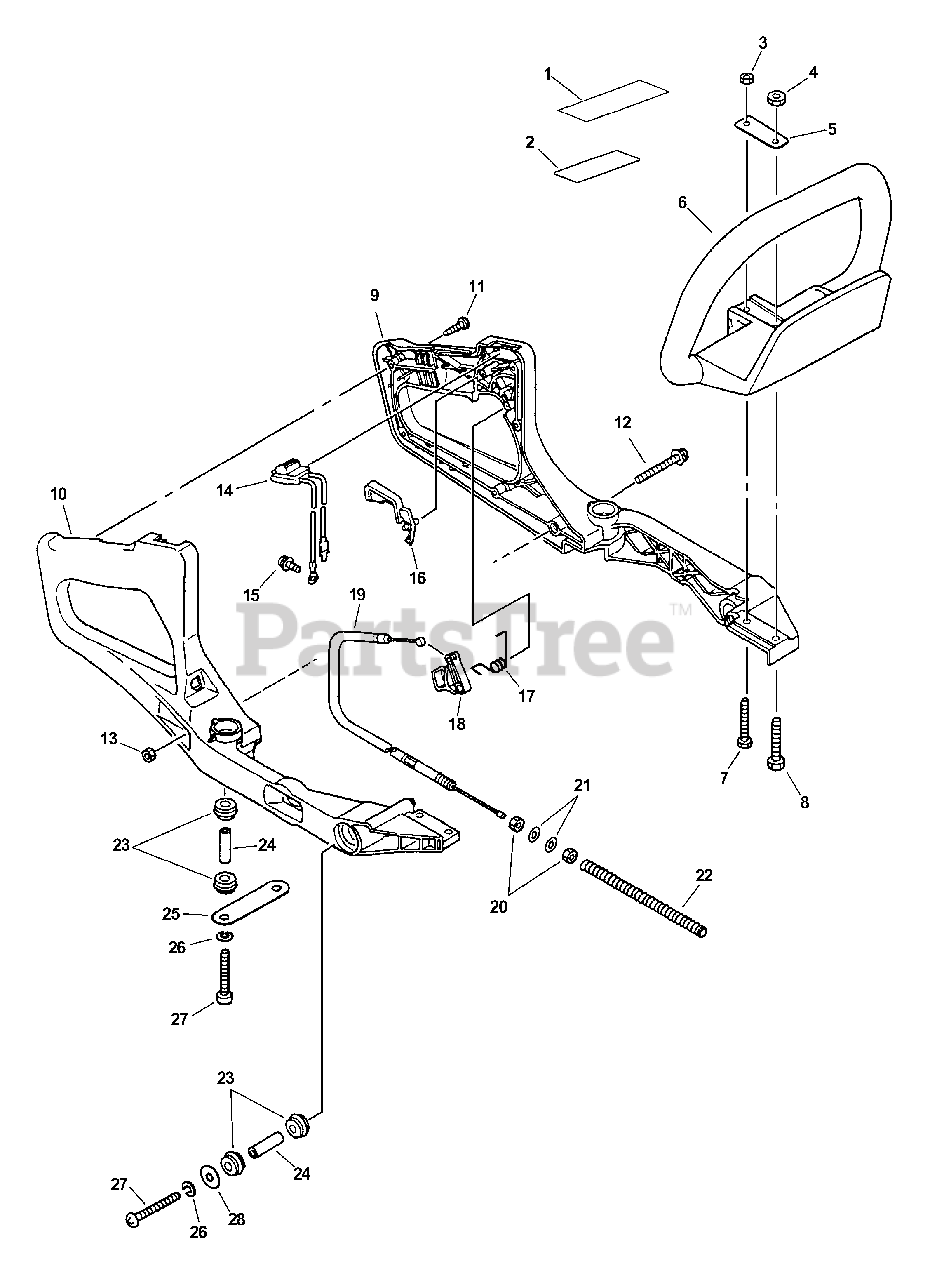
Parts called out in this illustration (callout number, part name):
1	LABEL, CAUTION
2	LABEL, CAUTION
3	NUT M5
4	NUT, HEX M6
5	PLATE, EYE
6	HANDLE, SUPPORT
7	BOLT 5×35 SP
8	BOLT - 6×32
9	HANDLE, REAR - LEFT
10	HANDLE, REAR - RIGHT
11	SCREW 4×25
12	SCREW 5×64
13	NUT M5
14	IGNITION SWITCH ASSY
15	SCREW 5×10
16	LOCKOUT, THROTTLE
17	SPRING, TORSION
18	TRIGGER, THROTTLE
19	CABLE, THROTTLE
21	WASHER 6.5×11.5×0.8
24	SPACER
25	PLATE, EYE
26	WASHER, SPRING 5
27	SCREW 5×40
